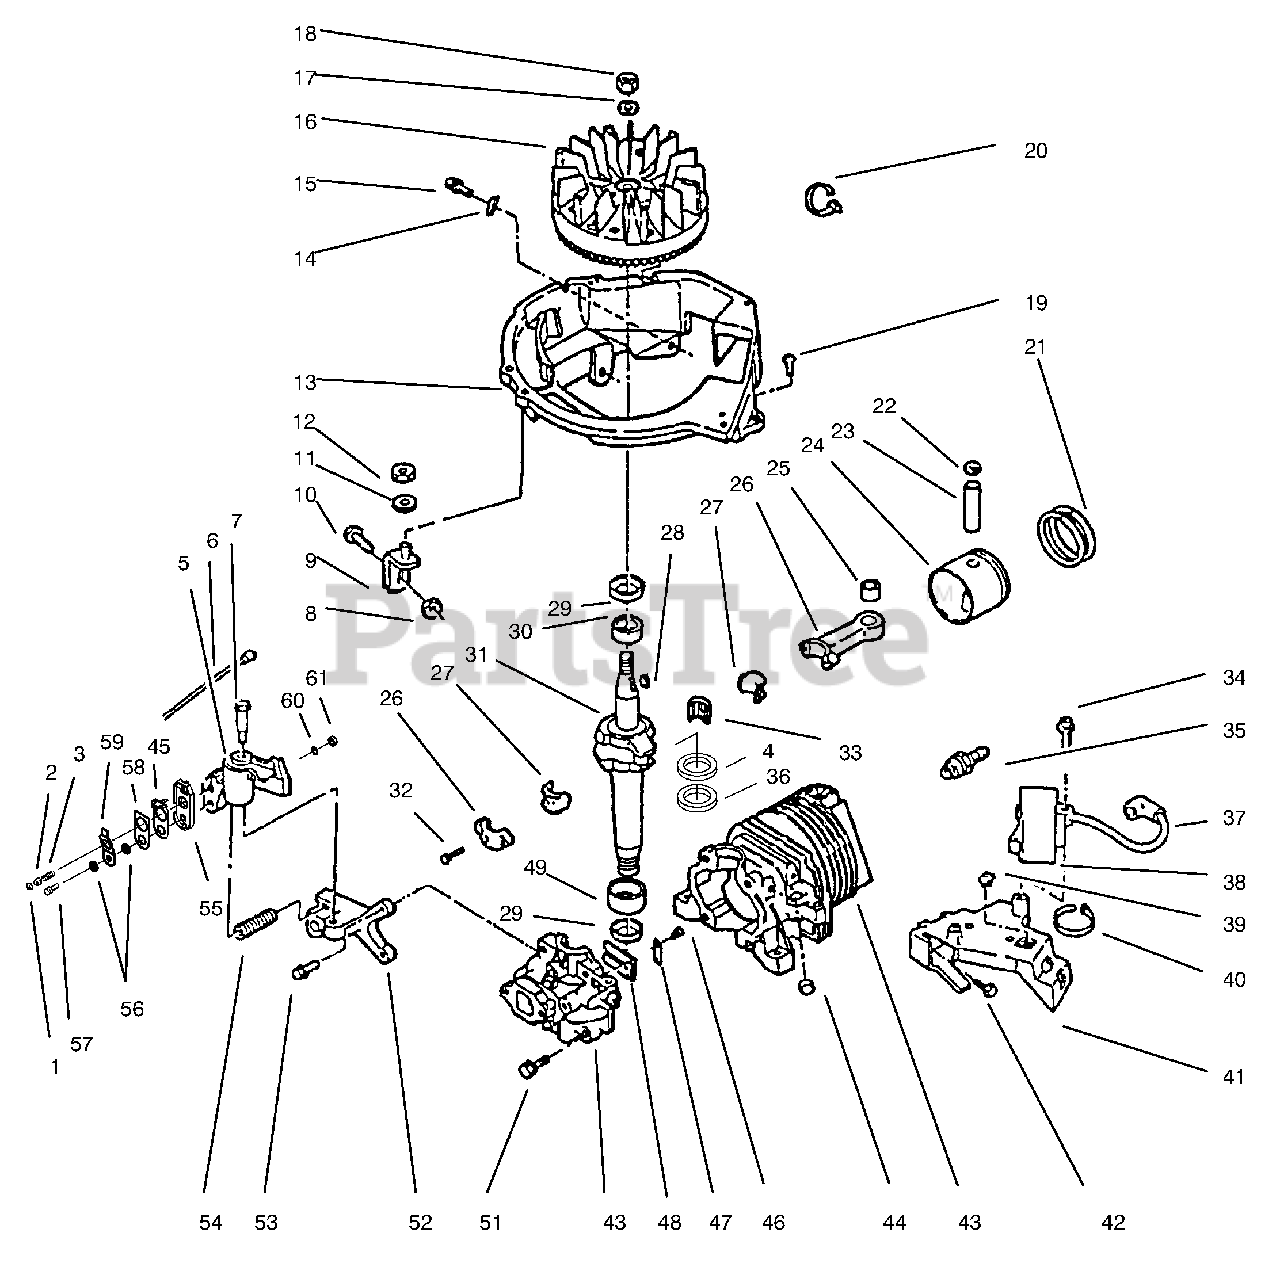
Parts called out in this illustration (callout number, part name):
1	Retainer
2	Actuator-Brake Lever
3	Spring-Cable, Return
4	Bearing-Thrust
5	Brake Assembly
6	Wire Lead
7	Bolt-Shoulder
9	Brace Assembly
13	Shroud-Base
14	"J"Clip
16	FlywheelAssembly
17	Washer-Lock
18	Nut-Flywheel
20	Tie Strap
21	Set-Ring
22	Ring-Retaining
23	Pin-Wrist
24	Set-Piston & Ring (Incl. Ref.# 21-24)
25	Bearing Assembly
26	Connecting Rod Assembly (Incl. Ref. #25, 27,32 & 33)
27	Liner-Pair
28	Key-Flywheel
29	Seal-Oil
30	Bearing-Main
31	Crankshaft
33	Set-Needle Bearing
34	Screw
35	Spark Plug
36	Waxher-Thrust
37	Wire Lead & Cover Assy
38	C.D. Ignition Module (Incl. Ref. #37)
39	Grommet
40	Tie Strap
41	Bracket-C.D.
43	Cylinder & Crankcase Cover Assembly (Incl. Ref. #46-48,51 & 53)
45	Plate-Contact
47	Plate-Reed
49	Bearing-Main
52	Bracket-Brake
54	Spring-Brake
55	Case Assembly
56	Washer
59	Spring-Contact
60	Washer-Ext. Tooth Lock
61	Nut
